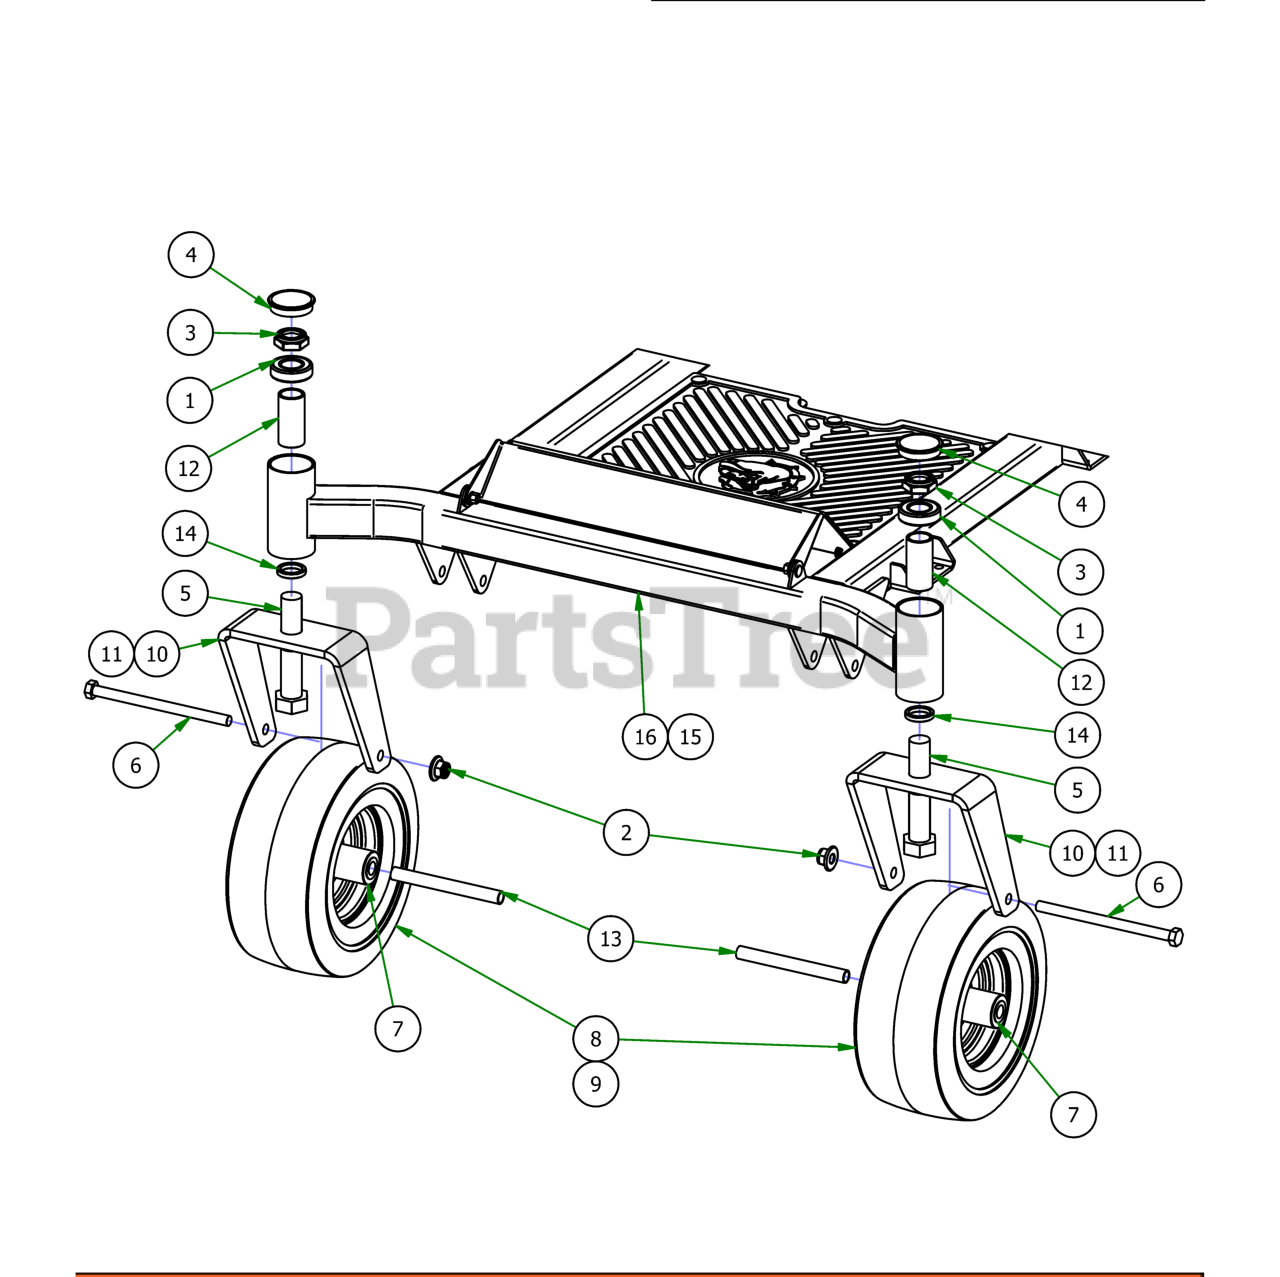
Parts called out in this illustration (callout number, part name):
1	Caster Bearing 2016 - 1641 Bearing
2	1/2-13 Nylon Flange Nut
3	1" Fine Thread 1/2 Nylock Nut
4	2017 Bearing Cover
5	1-14 x 5 Hex Bolt Grade 8 Zinc Yellow
6	1/2 -13 x 7.5 Hex Bolt Grade 5
7	Front Wheel Bearing
8	11x6-5 front tire & wheel assembly (Kenda)
9	11x4-5 MZ Front Tire Assembly (42" MZ Only)
10	2017 MZ Front fork
11	MZ 8mm Front Fork (42" MZ Only)
12	2016 Front Bearing Spacer
13	Front Wheel Spanner
14	Spacer, 1x1.375x.25
15	2017 MZ/ZT 54"-60" Frame
16	2017 MZ/ZT 42"-48" Frame
